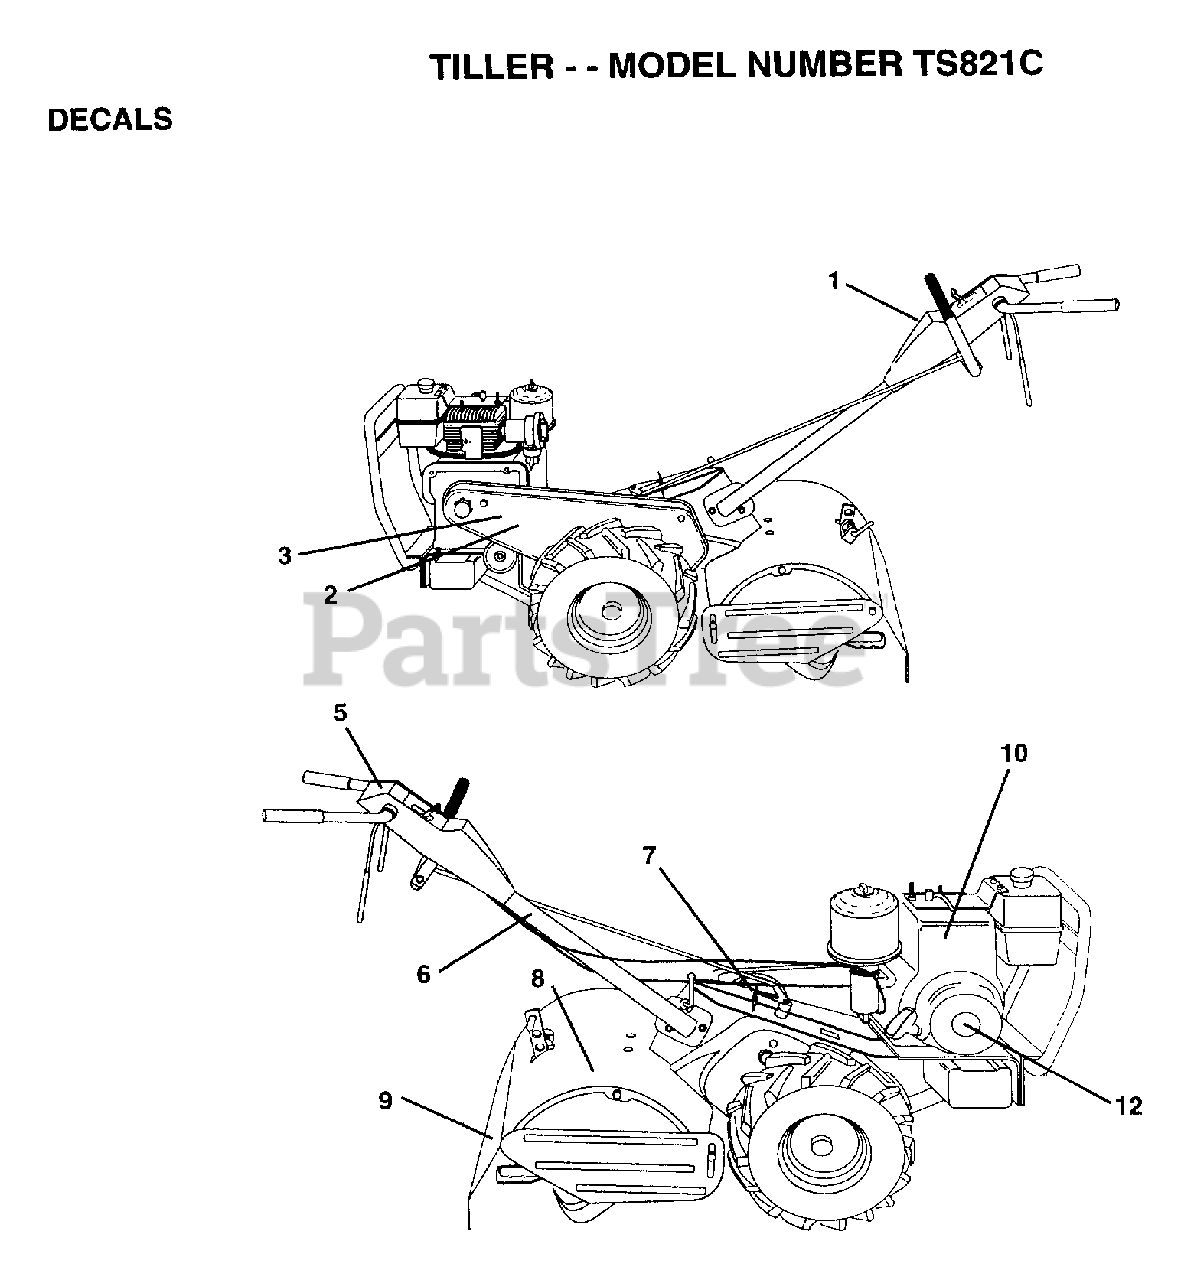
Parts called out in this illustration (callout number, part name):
1	DECAL.PNL.CTRL.
2	NAMEPLATE.HUSKEE
3	DECAL.GUARD.BELT
5	DECAL.INST.PNL.CT
6	DECAL TI
7	DECAL.SHIFT.IND.
9	DECAL TI
10	DECAL.ENG.B&S.8HP
12	DECAL.ENG.B&S.8HP
